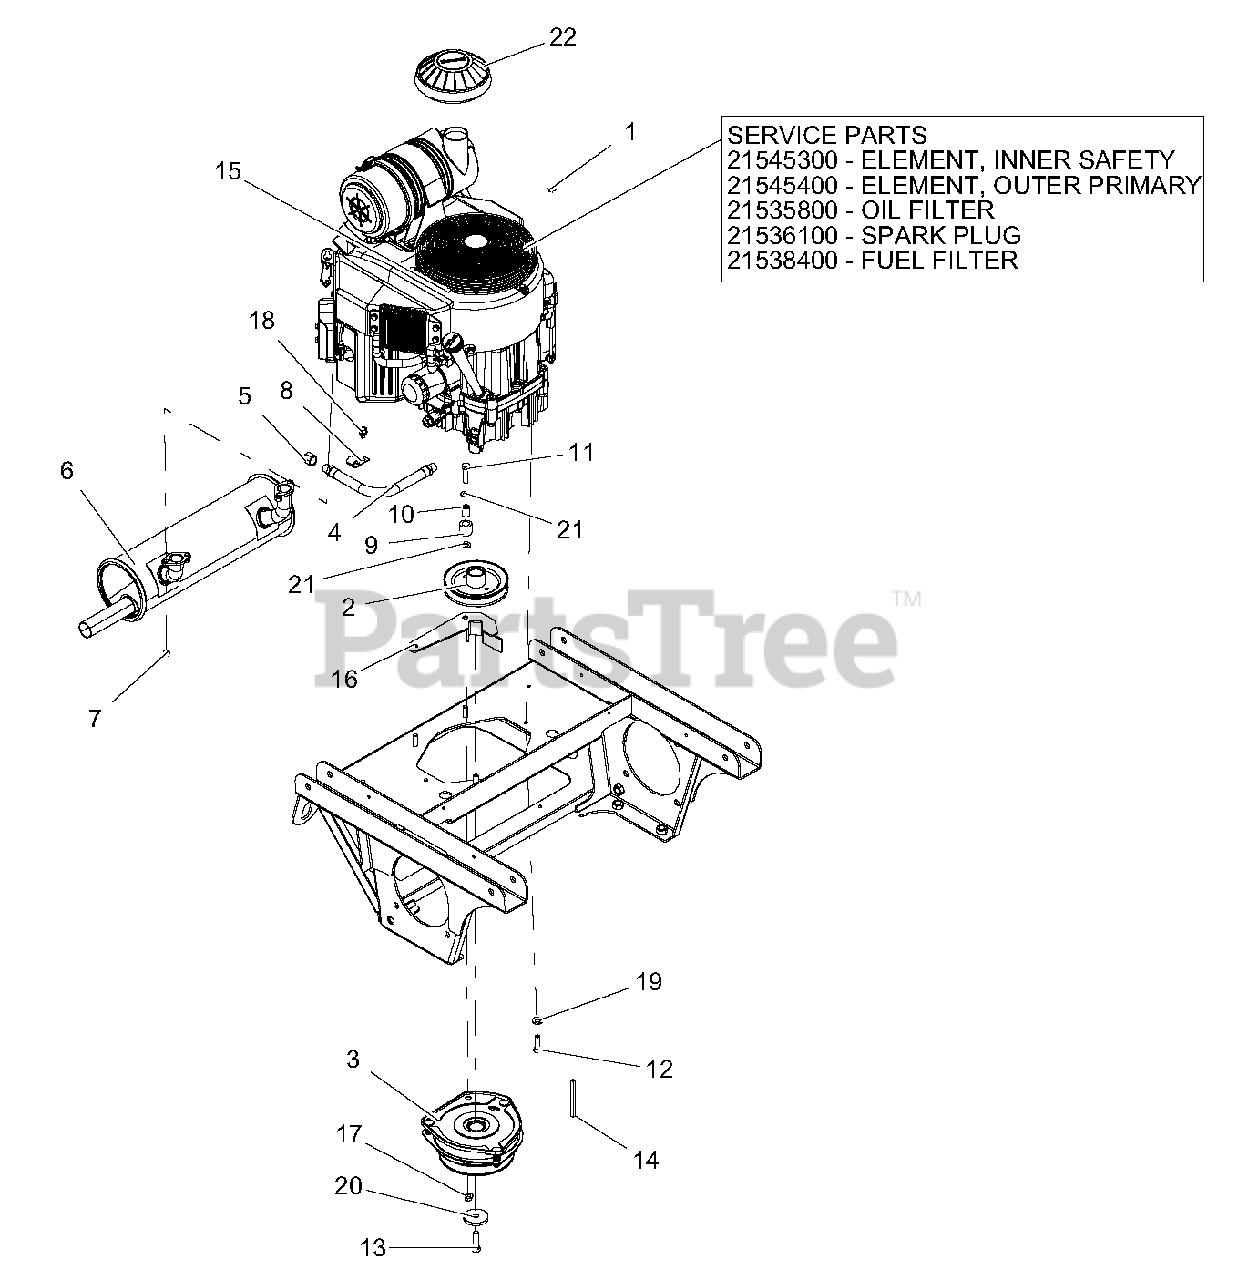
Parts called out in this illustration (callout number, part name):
1	CLAMP, FUEL LINE
2	SHEAVE, ENGINE 1.127 ID X 5.250 OD-BLACK
3	CLUTCH-OGURA
4	HOSE, HYD .38-11-OK M6N0-M6N0-YELLOW
5	PIPE, CAP 3/8 NPT FEMALE
6	MUFFLER, 27-31 FX KAW
7	NUT-LK-TOP M8-1.25 YWZC
9	BUMPER, RUBBER .62 X 1.0 X .88 LG
10	BUSH., S .407X.625X.813 ST REV A
11	BLT-HEX .38-16X1.50 GR5 YWZC
12	BLT-HEX .38-16X1.25 GR5 YWZC NYTORQ
13	BLT-HEX .44-20X1.50 GR8 YWZC
14	KEY-SQ .250X.250X3.50
15	ENGINE, KAWASAKI FX850
16	WMT, CLUTCH STOP
17	@NUT, LK-TOP-FLG .38-16 YWZC
18	SCR-TAP .38-16X.50 HWH TR YWZ
19	WSHR, 3/8" SPRING DISC
20	WSHR-FL-STL .469X2.00X.25 YWZC
21	@WSHR-FL-STL.406X.812X.065 YWZ
22	CAP, AIR CLEANER INTAKE (2")
